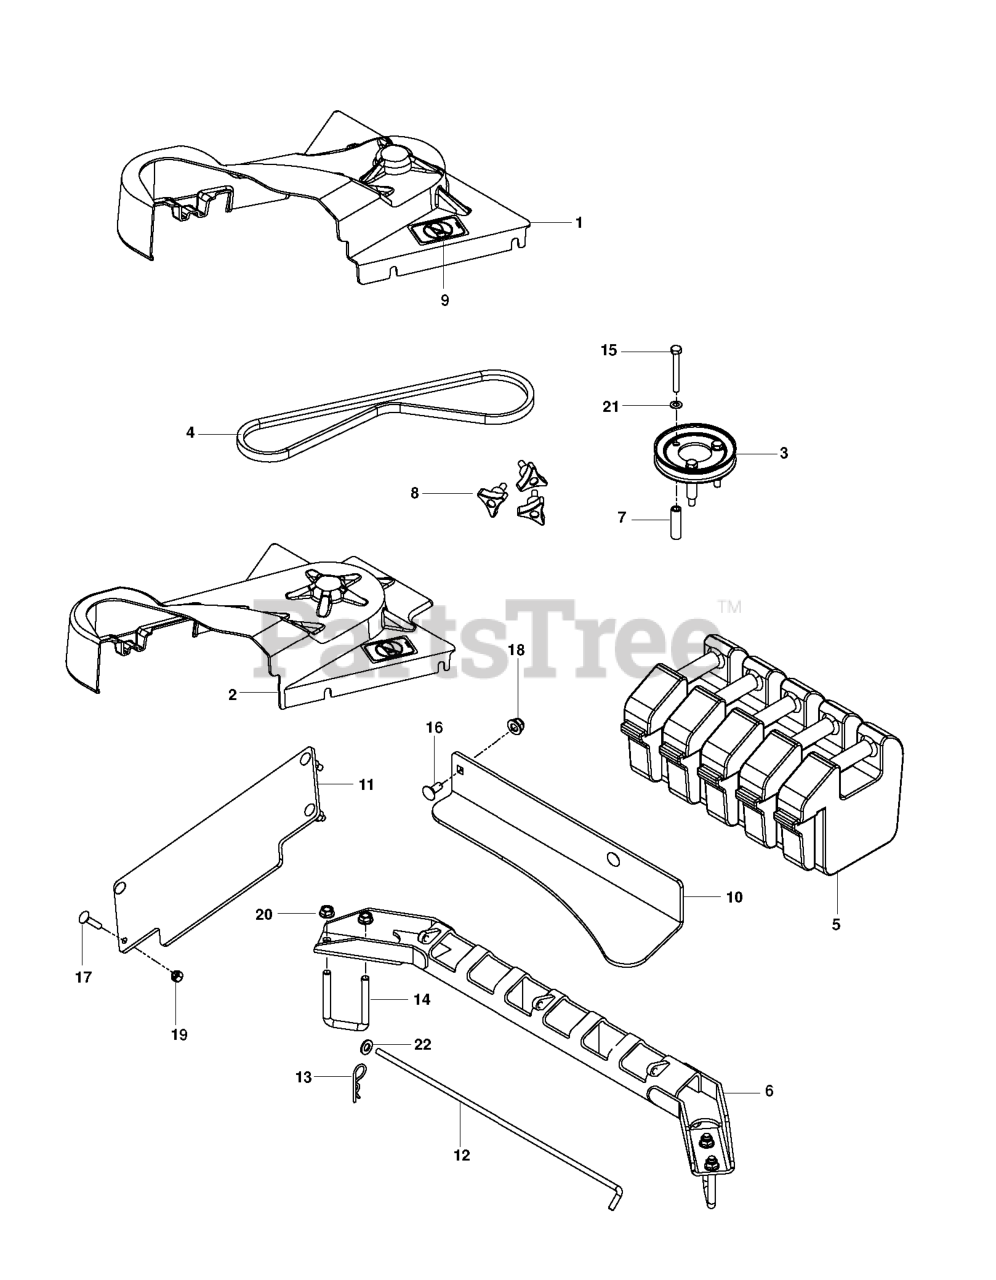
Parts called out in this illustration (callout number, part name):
1	SHIELD, LOWER, 54"
2	SHIELD, LOWER, 60"
3	PULLEY, DRIVE, 54"
4	BELT, DRIVE RAKE/SLICER DFS
5	FRONT WEIGHT CAST PZ DFS
6	BRACKET.MTG.CNTRWT.SIX.BLK
7	SPACER, PULLEY
8	KNOB W/STUD
9	DECAL, NO STEP
10	BAFFLE, RH, BLACK
11	BAFFLE, LH, BLACK
12	ROD.LATCH.BLK
13	HAIRPIN #4
14	U-BOLT.SQUARE.1/2-13.GR5
15	BOLT 5/16C X 2 1/2
16	BOLT 5/16C X 3/4" CARRIAGE
17	RHSNB, 1/4-20 X 1, GR5
18	5/16-18 NYLOC FLANGE NUT
19	NUT.1/4-20.HEX.NYLOC.ZD
20	NUT, 1/2-13 HEX FLG NYLOC ZD
21	WASH 5/16 DISC SPRING ZD
22	WASHER 3/8 SAE FLAT
